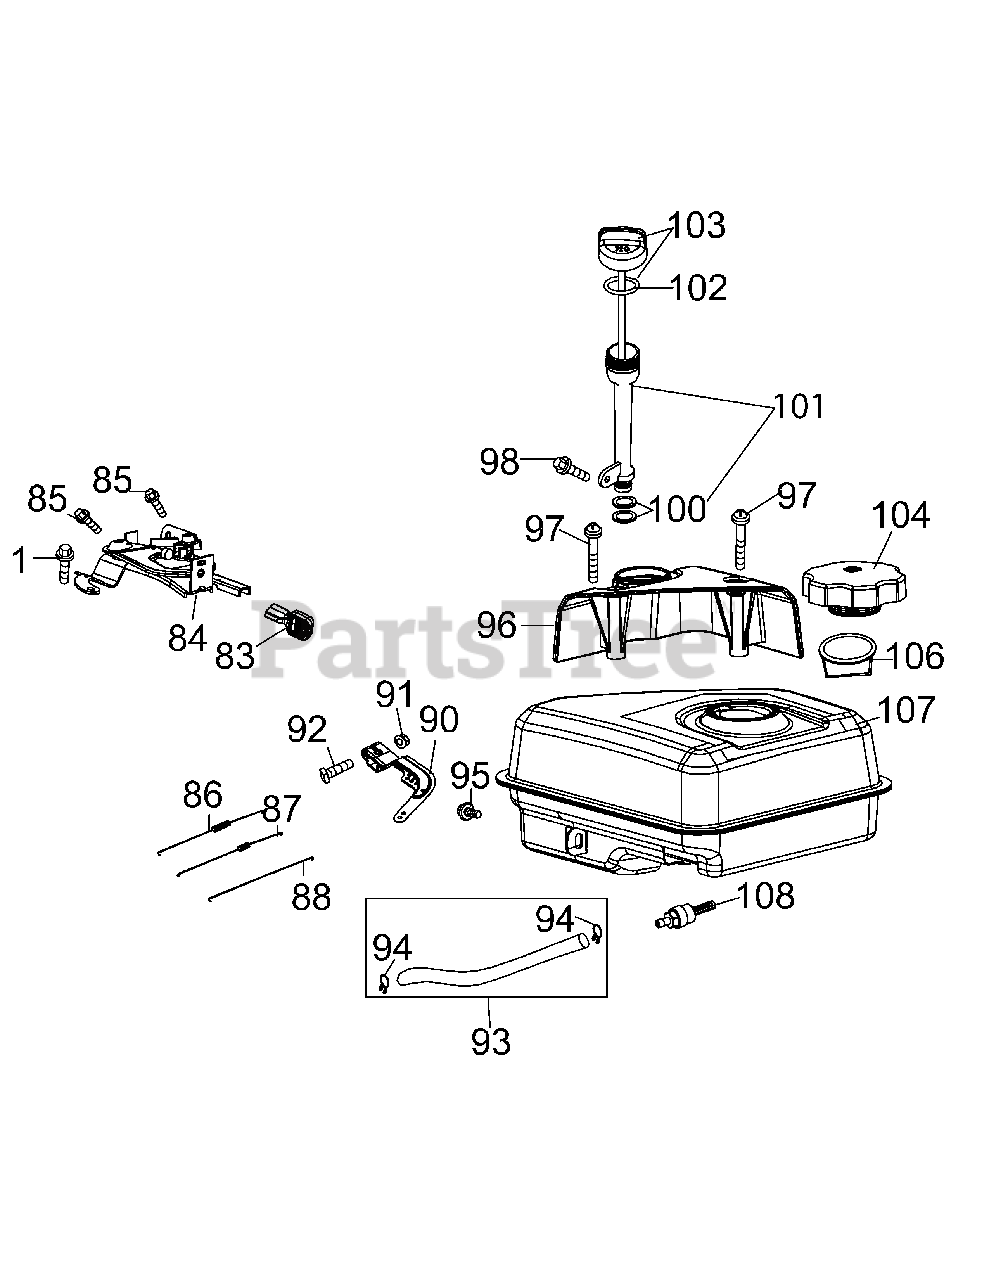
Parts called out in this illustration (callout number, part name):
1	Bolt M6×16
83	Throttle Control Knob
84	Primer Bracket
85	Bolt M6×12
86	Governor Spring
87	Throttle Linkage Spring
88	Throttle Linkage
90	Governor Arm
91	Nut M6
92	Governor Arm Bolt
93	Fuel Line Kit
94	Fuel Hose Clamp
95	Bolt M6×12
96	Dipstick Decoration Cover
98	Bolt M6×12
100	Oil Fill Tube O-Ring
101	Oil Fill Tube Assembly
102	Oil Fill Tube O-Ring
103	Dipstick Assembly
104	Fuel Cap Assembly
106	Fuel Level Indicator
108	Fuel Tank Nipple
